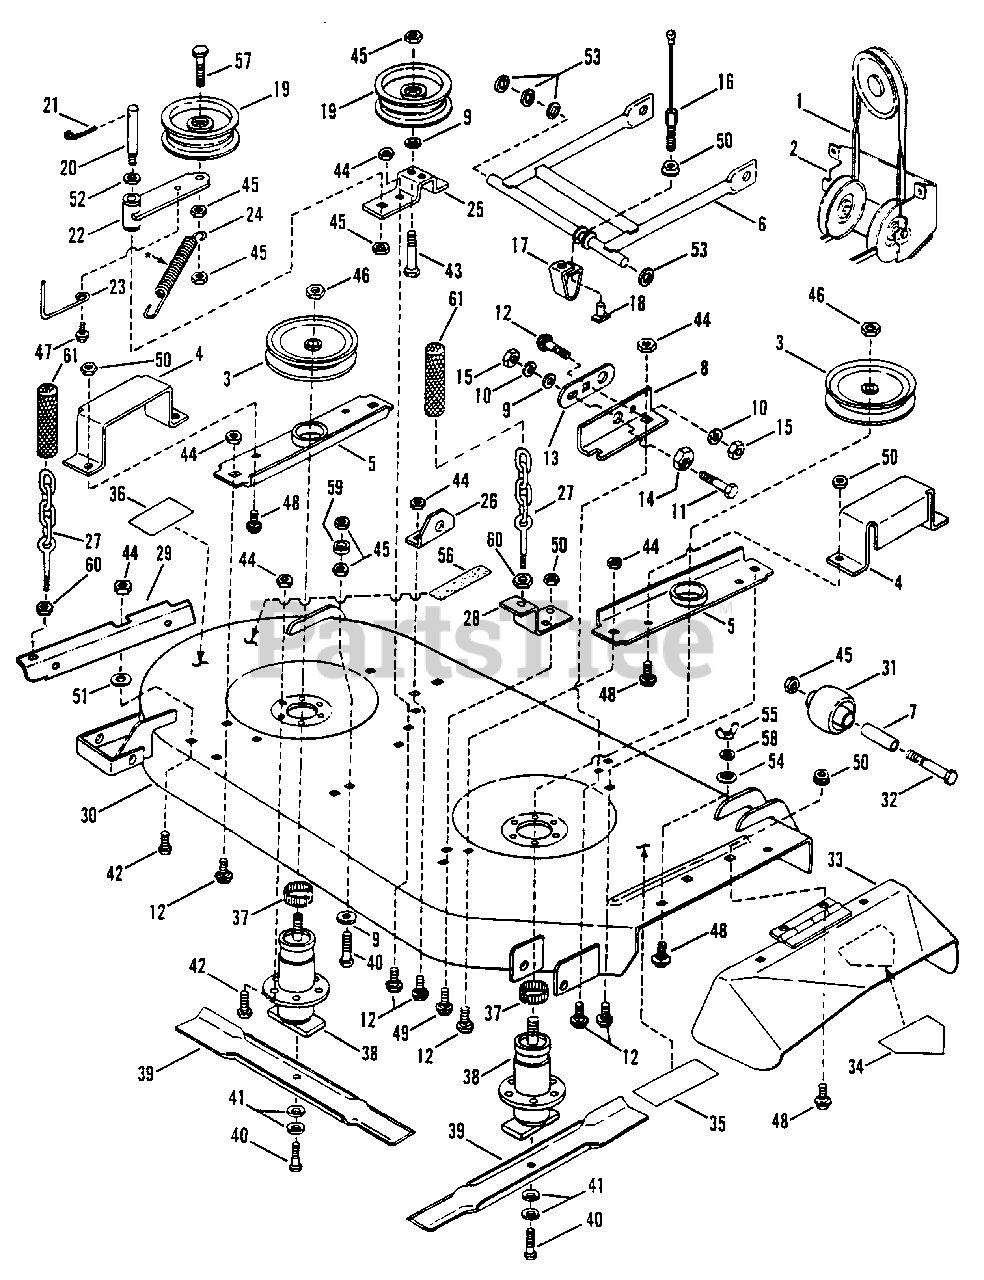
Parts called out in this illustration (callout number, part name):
1	BELT, 42" Deck Drive
2	ASSEMBLY, Mule Drive
3	PULLEY, 5 3/4" O.D.
4	GUARD, Pulley
5	BRACE, Spindle
6	ASSEMBLY, Front Lift Arm
7	SPACER, Wheel
8	BRACKET, Right Front
9	WASHER, 3/8 SAE
10	WASHER, 3/8 Split Lock
11	SCREW, 3/8-16 x 1" Hex Head Cap, Grade 5
12	BOLT, 3/8-16 x 3/4" Carriage, Grade 2
13	LINK, Adjustment
14	RING, Adjustment
15	NUT, 3/8-16 Hex
16	CABLE, Front Lift
17	BRACKET, Front Lift Arm Hanger
18	T-NUT, 5/16-18
19	PULLEY, 4.1" O.D.
20	STUD, 3/8-24 Idler
21	COTTER-PIN, 1/8 x 1"
22	ASSEMBLY, Idler Arm
23	GUIDE, Belt
24	SPRING, Idler Arm
25	BRACKET, Idler
26	BRACKET, Left Front
27	ASSEMBLY, Adj. Bolt-Chain
28	ASSEMBLY, Bracket, Rear Lift, Right Side
29	ASSEMBLY, Bracket, Rear Lift, Left Side
30	DECK, 42" Cutter
31	WHEEL, Gage
32	SCREW, 3/8-24 x 3-3/4" Hex Head Cap, Gr.5
33	DEFLECTOR
34	DECAL, DANGER
35	DECAL, CAUTION, Deflector in Place
36	DECAL, CAUTION, Rotating Blades
37	RING, Tolerance, 3/4"
38	ASSEMBLY, Spindle
39	BLADE, 21"
40	SCREW, 3/8-24 x 1-1/4" Hex Head Cap, Grade 5
41	WASHER, Cone
42	BOLT, 3/8-16 x 3/4" Hex Flange Lock
43	SCREW, 3/8-24 x 1-3/4" Hex Head Cap, Grade 5
44	NUT, 3/8-16 Hex Flange Lock
45	NUT, 3/8-24 Hex Lock
46	JAM-NUT, 3/4-16 Hex Center Lock
47	SCREW, 1/4-20 x 5/8" Self-Tapping, Grade 5
48	BOLT, 5/16-18 x 5/8" Carriage, Grade 5
49	BOLT, 5/16-18 x 3/4" Carriage, Grade 5
50	NUT, 5/16-18 Hex Flange Lock, Grade 5
51	WASHER, 3/8" Flat
52	WASHER, 5/8 SAE
53	RING
54	RETAINER, 5/16 Bolt
55	WING-NUT, 5/16-18
56	FOOTPAD
57	SCREW, 3/8-24 x 2" Hex Head Cap, Grade 5
58	WASHER, 5/16 Split Lock
59	SPACER
60	NUT, 3/8-16 Hex Jam
61	COVER, Chain
